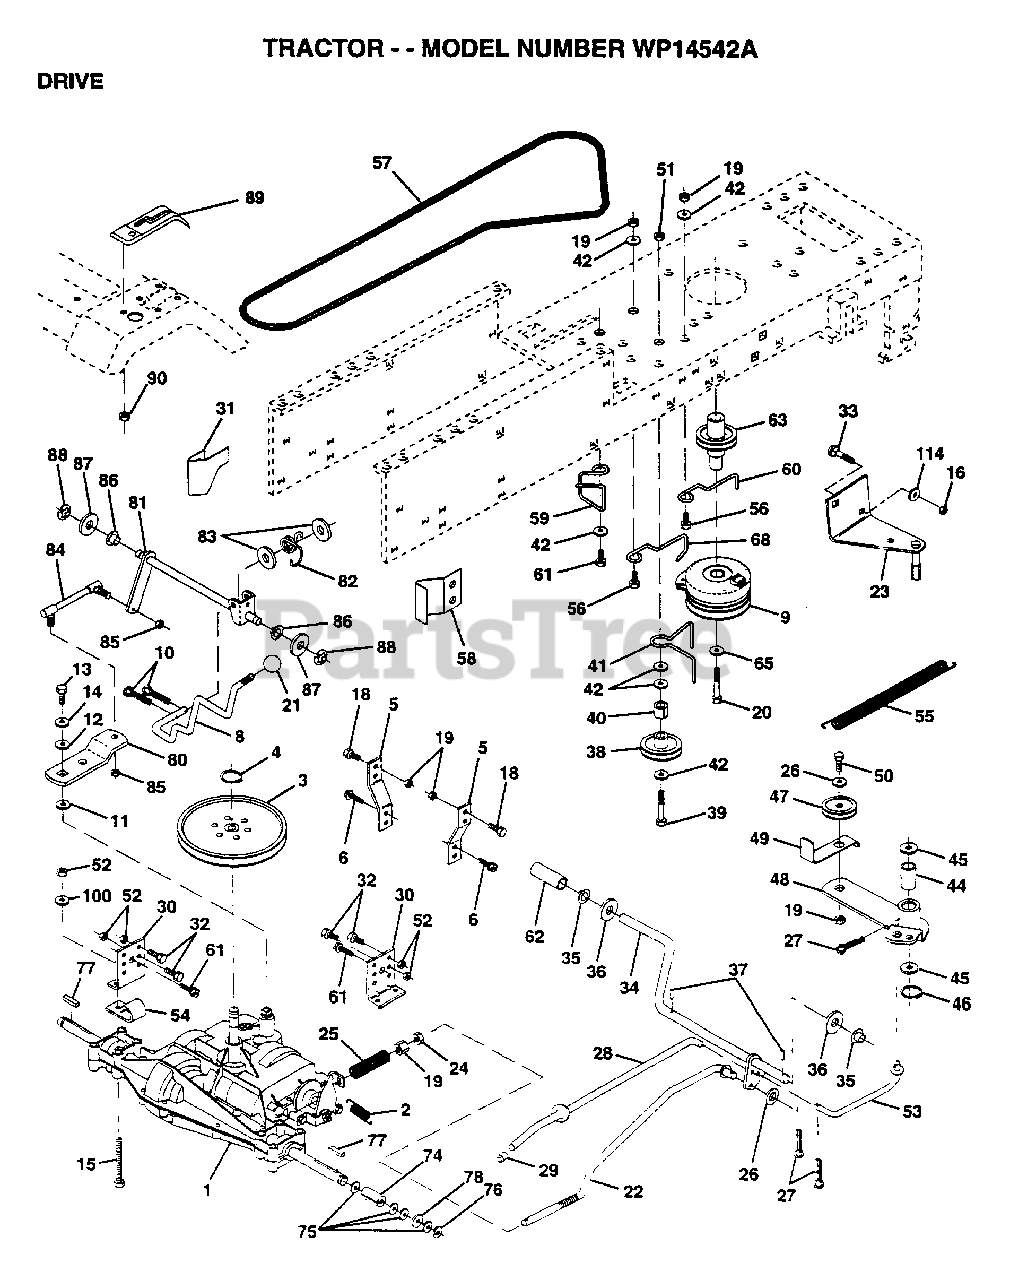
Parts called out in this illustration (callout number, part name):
2	SPRING.BRAKE.RETU
3	PULLEY TRANS
5	STRAP TORQUE
6	SCREW
8	ROD SHIFT FEND YT
9	CLUTCH.ELECT.EVX.
10	PIN COTTER 1/8
11	WASH-SHFT PLT LT
12	WASHER
13	BOLT.1/4-28.W/PAT
14	LOCKWASHER
15	BOLT HEX
16	NUT
18	BOLT
19	NUT
21	KNOB T (1/2-HOLE)
22	BRAKE ROD
24	NUT
25	SPRING ROD LT
26	WASHER
27	COTTER PIN
28	ROD.BRAKE.PARK.LT
29	PLUNGER CAP T
30	TRANSAXLE MTG BKT
31	"KEEPER,BELT LH T"
32	BOLT
33	BOLT T
34	SHAFT.PEDAL.FOOT
35	NYLON BEARING
36	WASHER LT
38	PULLEY.IDLER.FLAT
39	BOLT
40	SPACER T
41	BELT KEEPER LT
42	WASHER
44	"LY, BEARING"
45	WASHER LT
46	KLIP RING
48	ARM IDLER
49	RETAIN BELT
53	"LINK, CLUTCH T"
54	"CLIP,INSULATOR"
55	"SPRING, RETURN LT"
58	"KEEPER,BELT RH T"
59	KEEPER BELT CNTSP
60	KEEPER BELT ENGLH
61	SCREW
62	PEDAL COVER T
63	PULLEY.CLUTCH.EVX
65	LOCKWASHER
68	"KEEPER,BLT ENG LT"
74	SPACER LT
75	WASHER
76	E-RING LT
77	SQUARE KEY
78	WASHER
80	ARM SHIFT TRANS
81	SHAFT ASM.SHIFT
82	"SPRING,TORSION"
83	WASHER
84	TIE ROD
85	NUT 1/4-28
86	BUSHING
87	WASHER D
88	KLIP RING
89	CONSOLE SHIFT
90	NUT
100	WASHER M
114	WASHER
